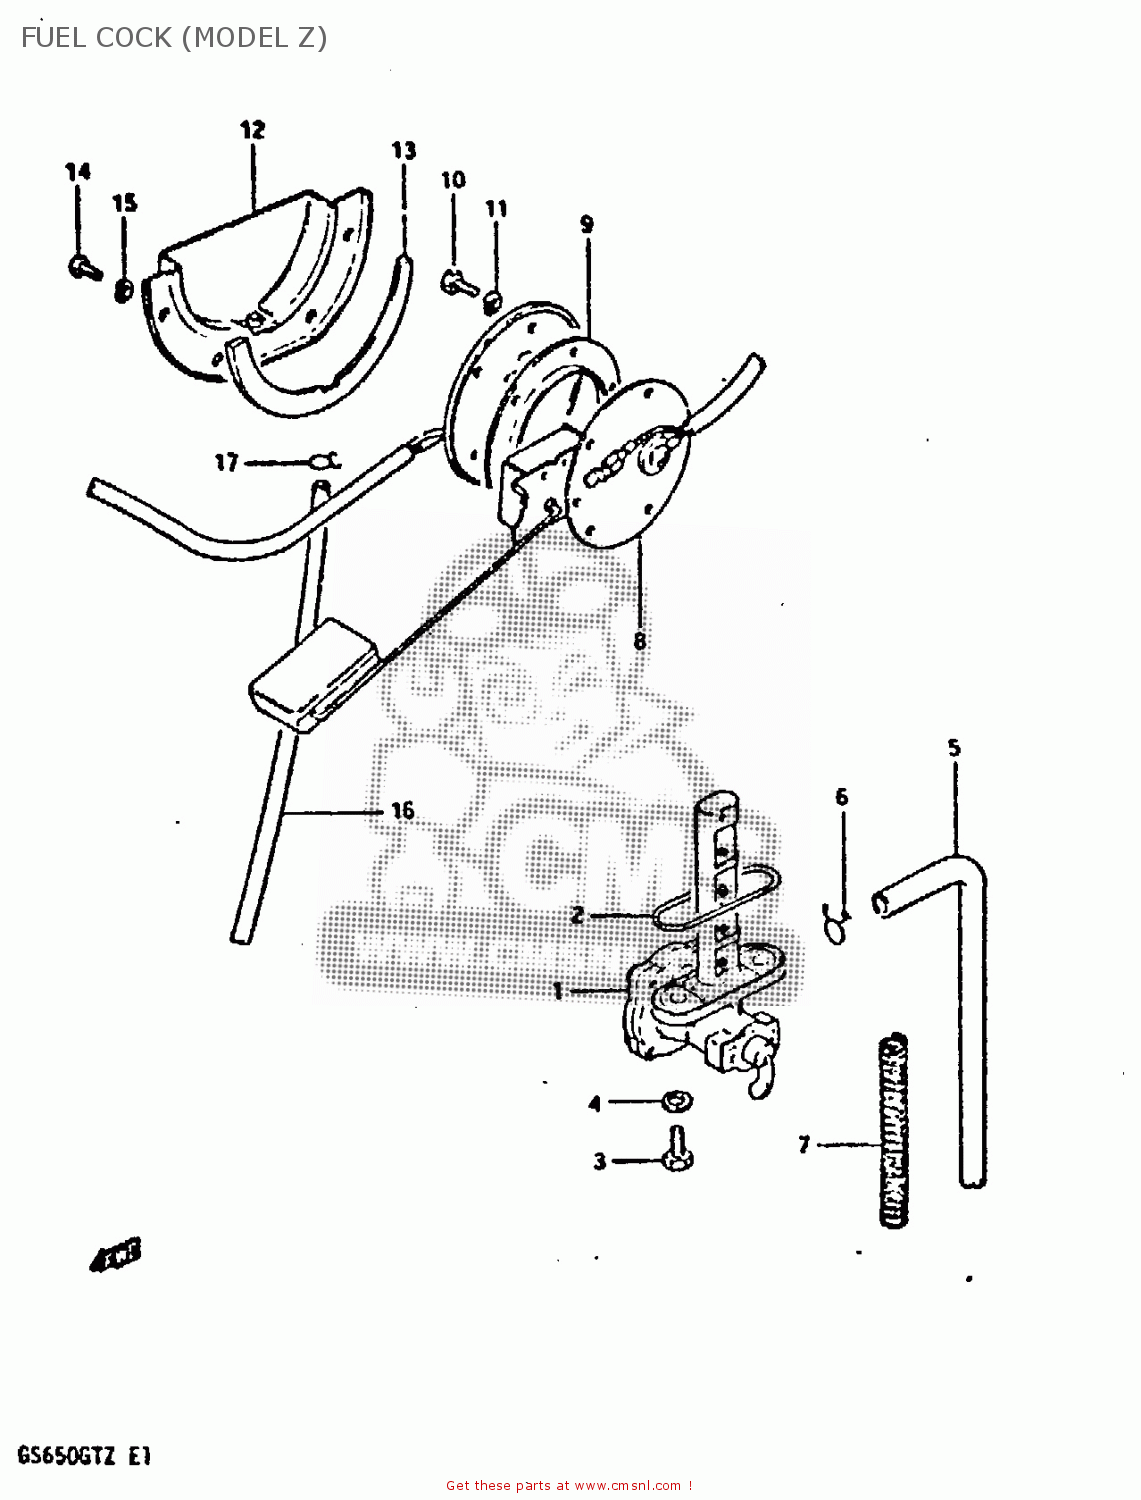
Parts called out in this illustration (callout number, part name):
1	COCK ASSEMBLY,FUEL
2	O RING
3	BOLT(6X20)
4	GASKET
5	HOSE
6	CLIP
7	SPRING
8	GAUGE ASSEMBLY,FUEL LEVEL
9	GASKET,FUEL LEVEL GAUGE (NAS)
10	BOLT
11	LOCK WASHER
12	PLATE,FUEL DRAIN
13	GASKET (NAS)
14	SCREW
15	LOCK WASHER
16	HOSE
17	CLIP
